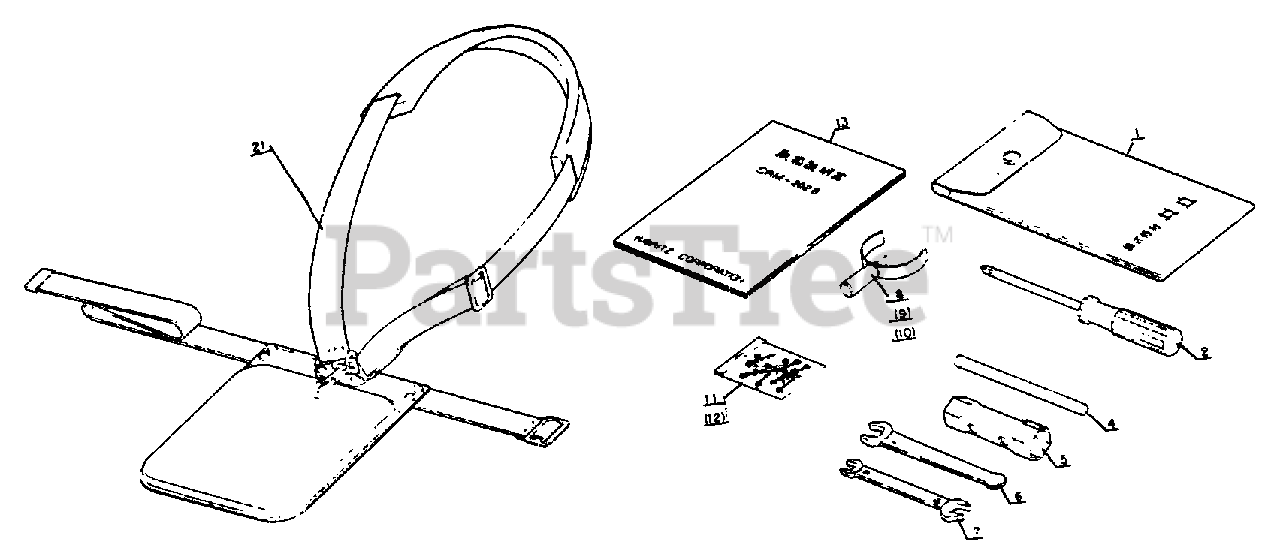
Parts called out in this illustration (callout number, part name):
1	BAG, TOOL
2	SCREWDRIVER - (+)
4	ROD, HANDLE
5	SOCKET WRENCH - 17X19mm
6	SPANNER - 13mm
7	SPANNER - 8X10mm
8	FITTING TOOL
11	PIN - 2X22
13	OWNER'S MANUAL
14	TOOL KIT
21	HARNESS ASSY
